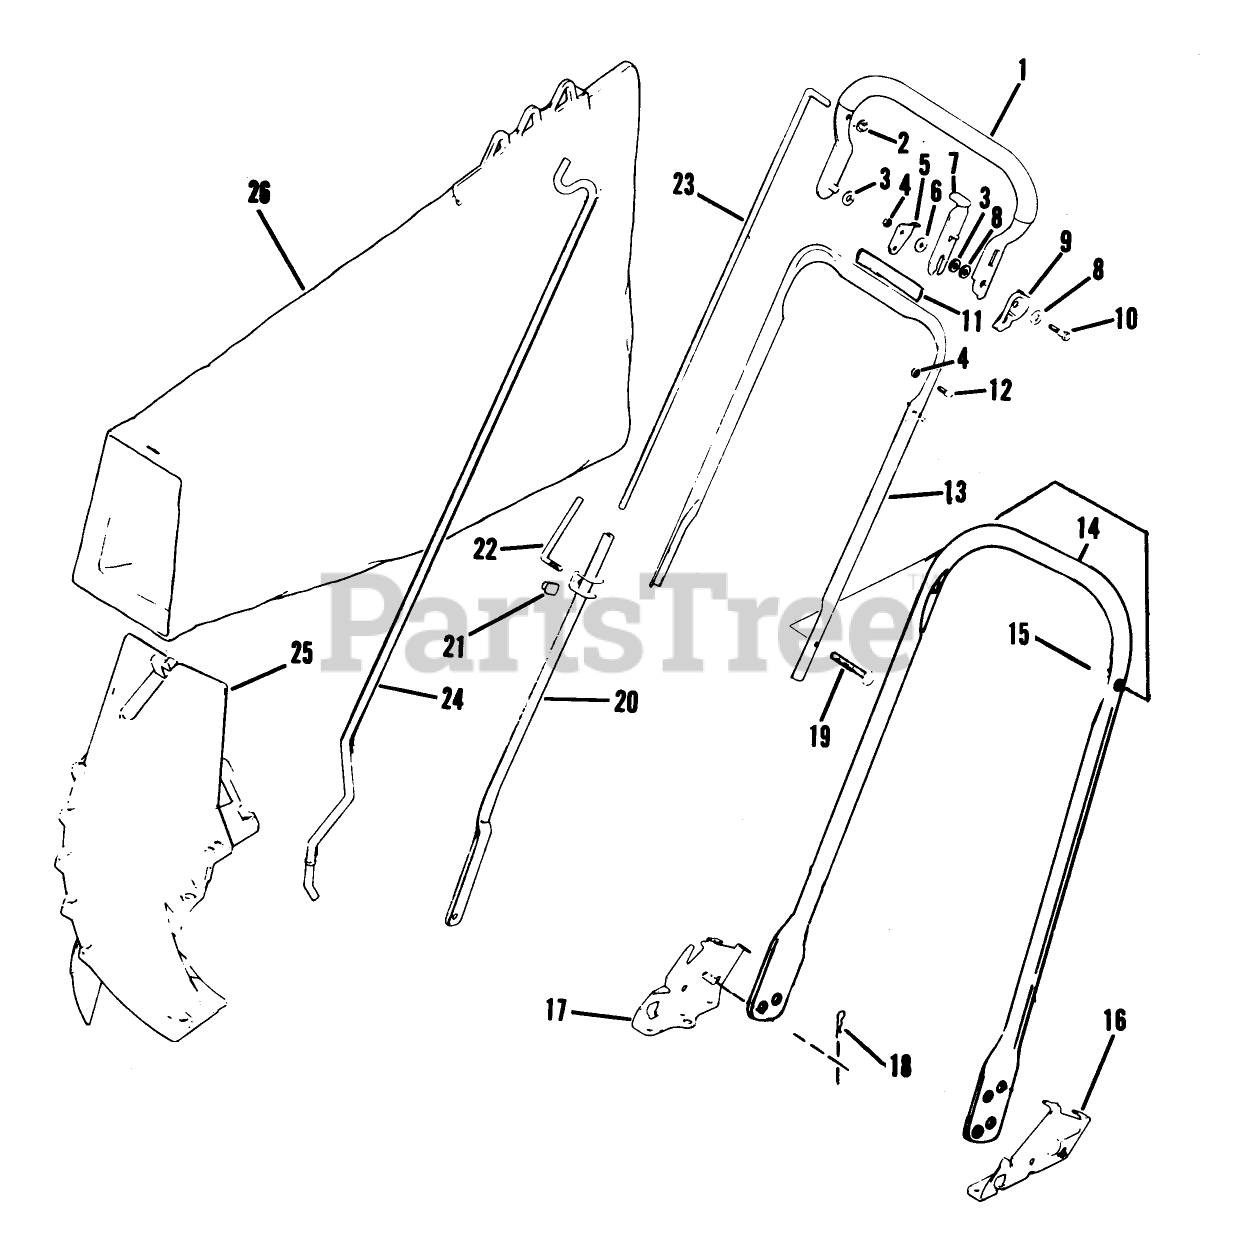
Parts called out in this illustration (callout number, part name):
3	WASHER M
4	LOCKNUT E
5	HANDLE STOP
10	BOLT PIONEER
12	SCREW-HANDLE STOP
13	Handle-Center
15	LOCKNUT E
18	HAIR PIN
19	SCREW - USE 137-3042
26	89802 LB WHOLE GOODS
